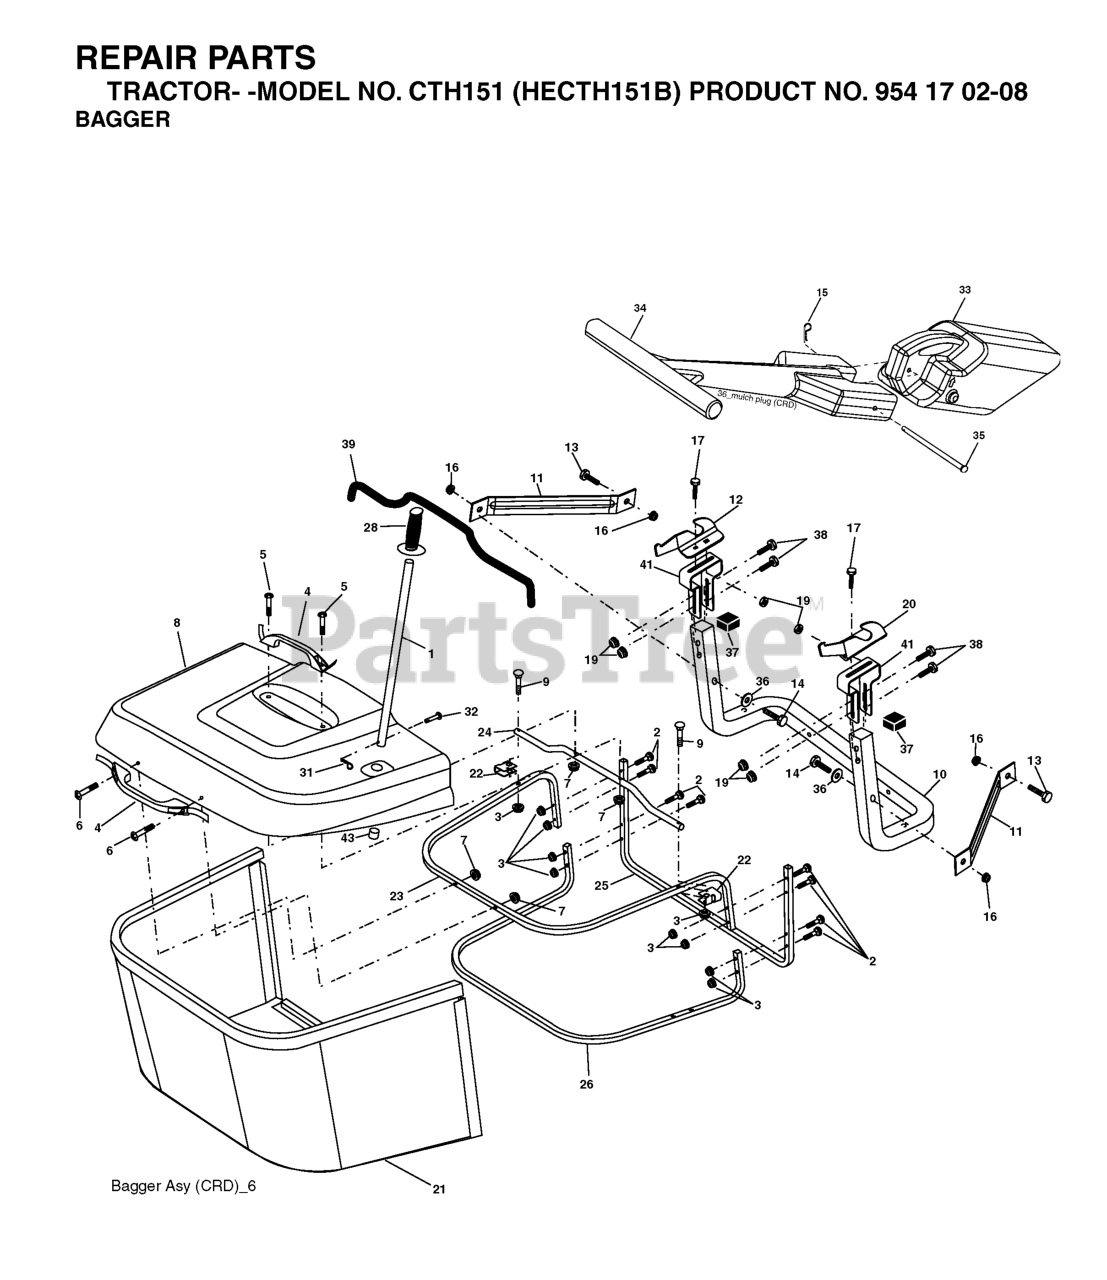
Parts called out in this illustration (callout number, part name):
1	TUBE HANDLE
2	Bolt Carriage 1/4-20 x 2.0 Gr.5
3	NUT T
4	HANDLE.BAGGER.W/LVRS.BLK.CRD
5	SCREW.PAN.HEAD
6	REPL BY 532 75 00-29
8	COVER.PNT.BGR.CRD.WSLOTS.MS668
9	Bolt Carriage 1/4-20 x 2.25d x Gr.5
10	TUBE
11	BRACKET.SUPPORT.UPPER.BAG.CRD
12	BRKT PIVOT
14	BOLT-HEX EAK
16	NUT LOCK FLG 3/8-16 UNC
17	RP BOLT 5/16-18 X3/4 ZN/YEL GR
18	WASHER M
19	NUT LOCK HEX FLANGE 5/16-18
20	BRKT.PIVOT.RH.CRD
21	GRASS BAG
22	BRKT.SIDE.BAG.CRD
23	TUBE.UPPER.BAG.CRD
24	TUBE.PIVOT.BAG.CRD.BLACK
26	TUBE.LOWER.BAG.CRD
28	GRIP.HANDLE.BLACK
31	RETAINER CLIP
32	RIVET,DRILLED
33	PLUG.MULCHER.92 CRD
34	HANDLE.MULCHER.92.CRD (2 2)
36	WASHER
37	Plug Support Bagger CRD
38	BOLT.5/16-18X2.5
39	SEAL.TRIM.37'
41	BRKT.VERT.ADJ.BAGGER.CRD
42	NUT.71038.31-18.HEX.NYLOCK
43	PLUG, TUBING END
